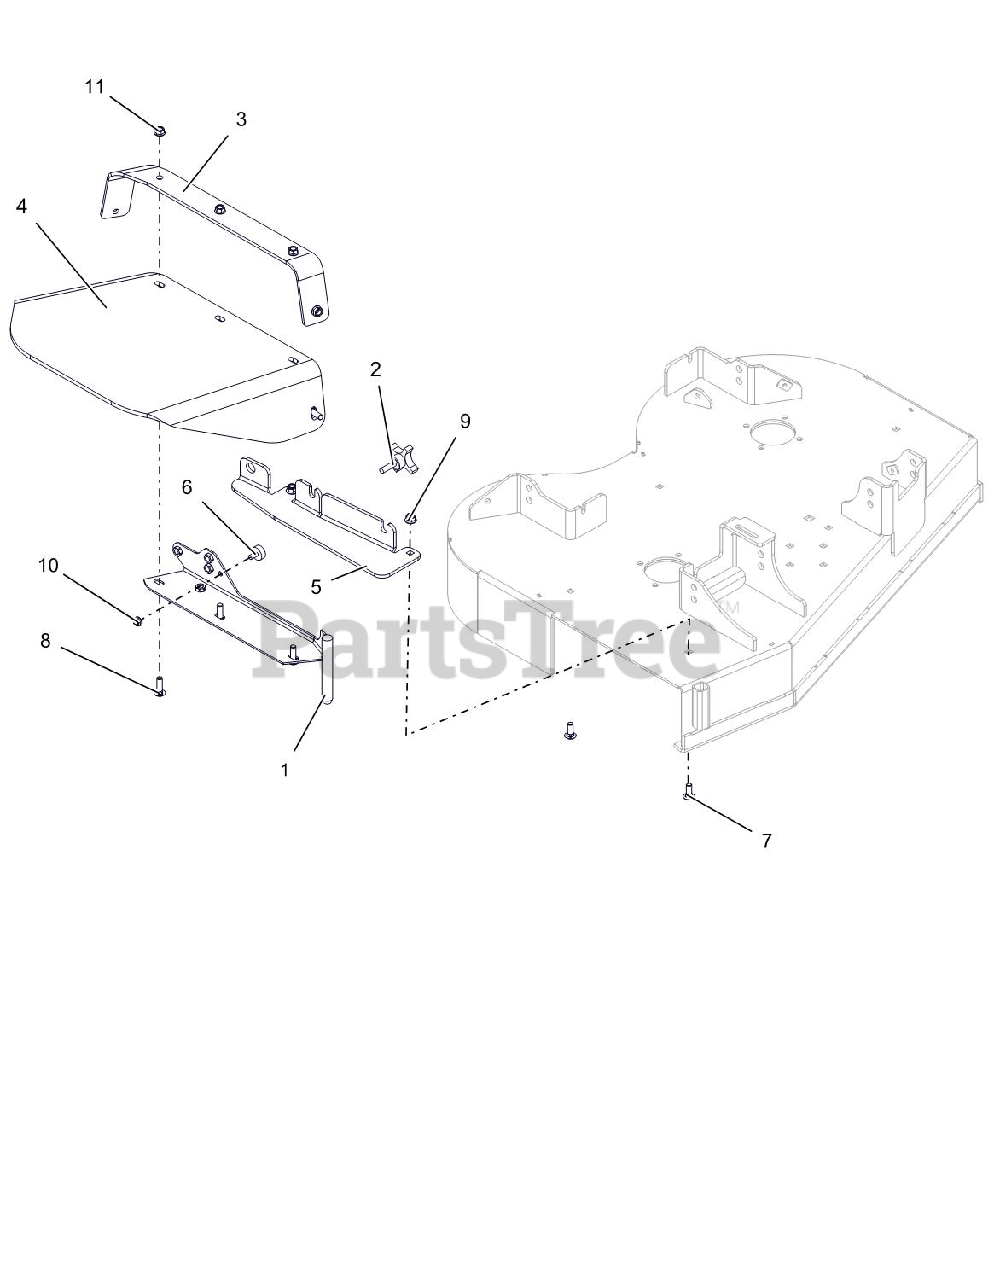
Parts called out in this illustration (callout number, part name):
1	WLDT. DISCHARGE
2	KNOB, 3/8 X 1.25 - 4 PRONG
3	STRAP, RUBBER DISCHARGE CHUTE
4	SHIELD, RUBBER DISCHARGE
5	BRKT, 36 STANCE DISCHARGE
6	BUMPER, RUBBER
7	@BLT-RDHDSQNK .38-16X1.00 G5YZ
8	@BLT-RDHDSQNK .38-16X1.25 G5YZ
9	@NUT-LK-NYL-FLG .38-16 YWZC
10	@NUT-SPNLK-FLG .312-18 YWZC
11	@NUT-SPNLK-FLG .375-16 YWZC
